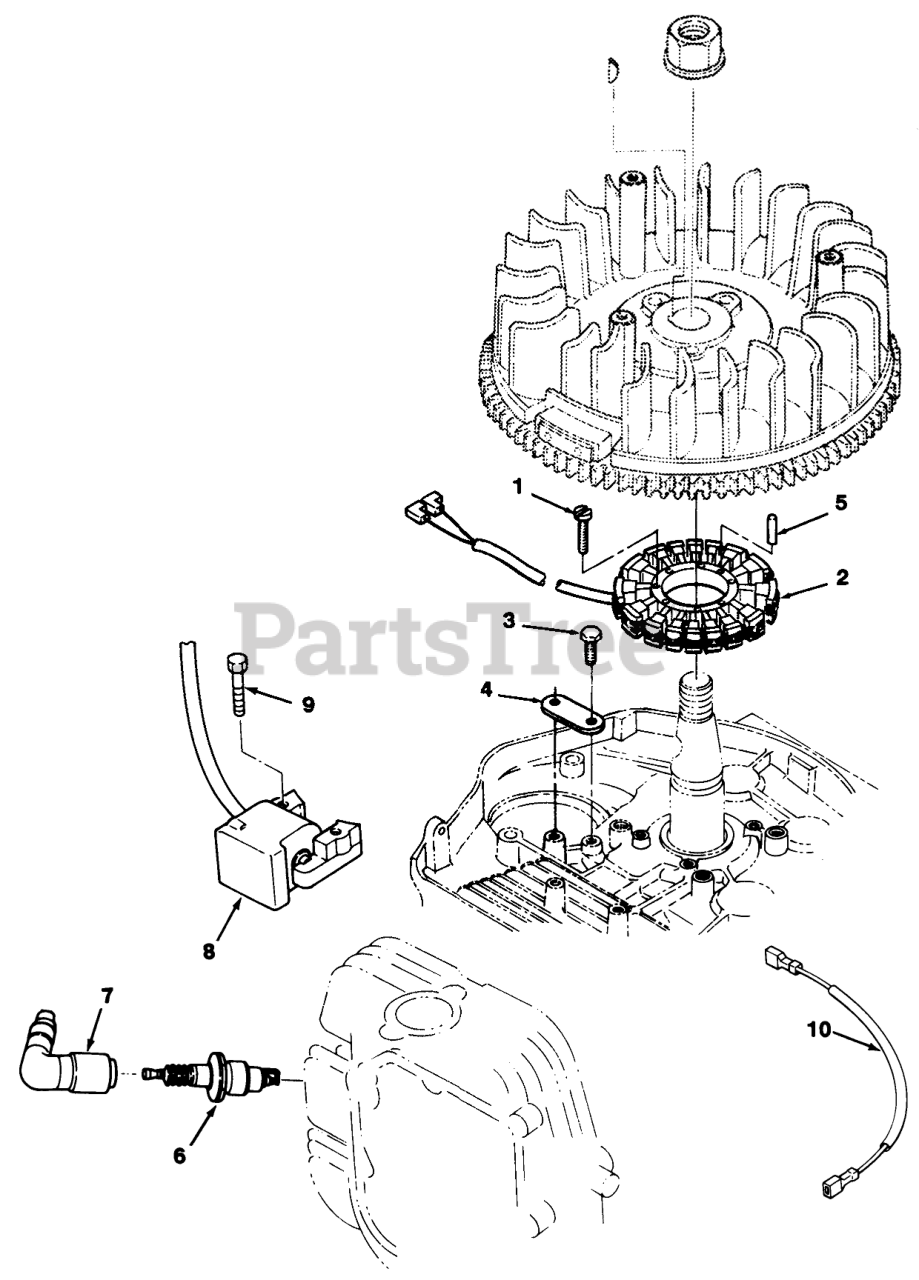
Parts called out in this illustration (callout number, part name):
1	SCREW
2	STATOR
3	HHSTB-M6 X 14MM
4	CLAMP-CORD
5	PIN-ALIGNMENT
6	SPARK PLUG
8	COIL-IGNITION
9	HHSTB-M6 X 27MM
10	HARNESS
